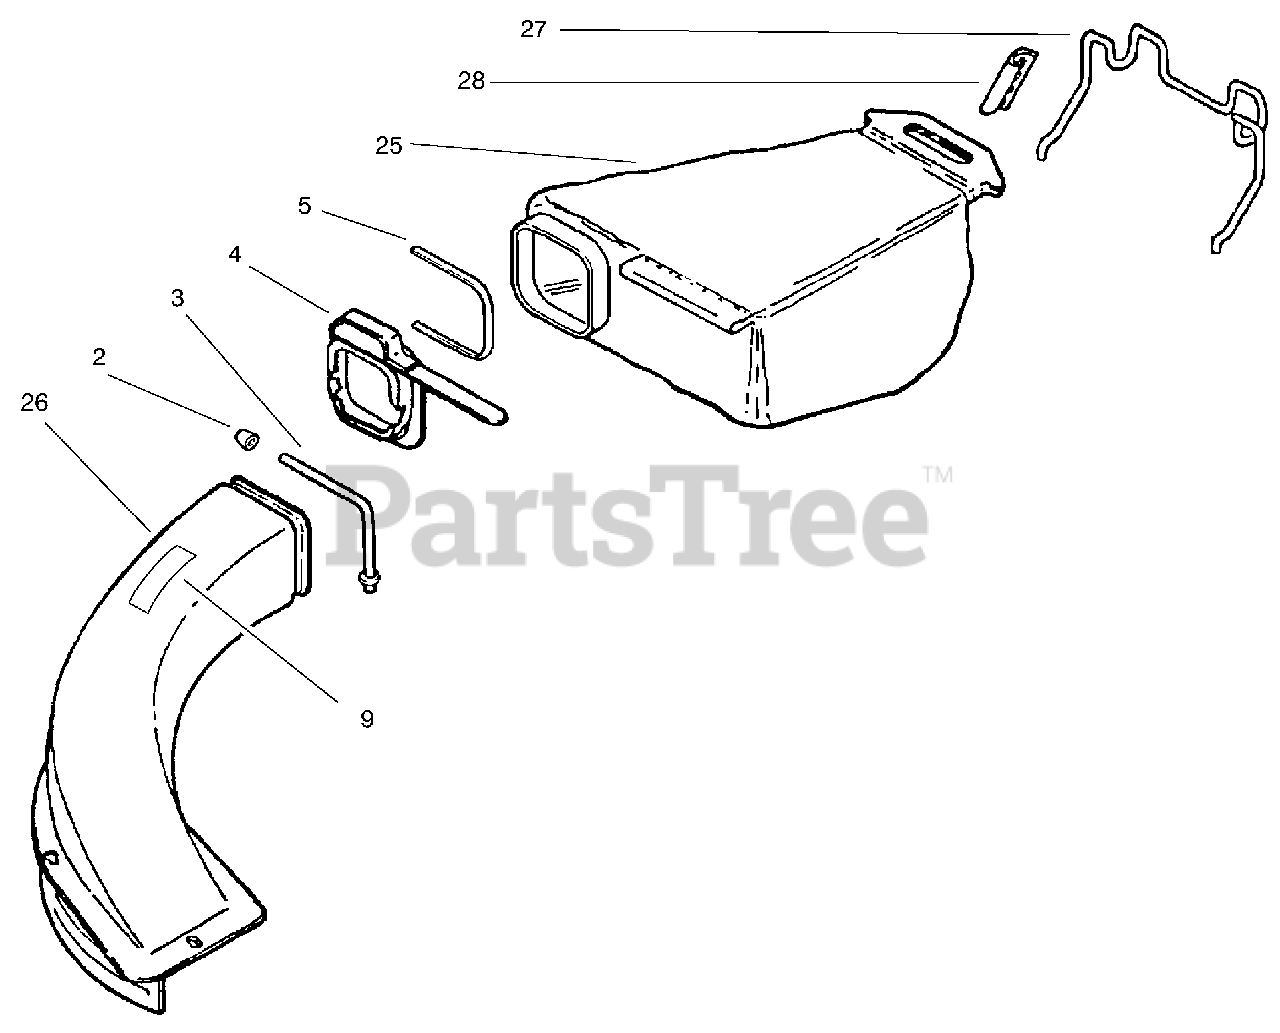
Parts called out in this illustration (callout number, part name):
2	Nut-Cap
3	Support-Chute
4	ASM-Adaptor
5	Tie Strap
9	Decal-Danger
25	ASM-Bag & Adapter
26	ASM-Chute & Support
27	Hanger-Wire
28	Hanger-Clamp
